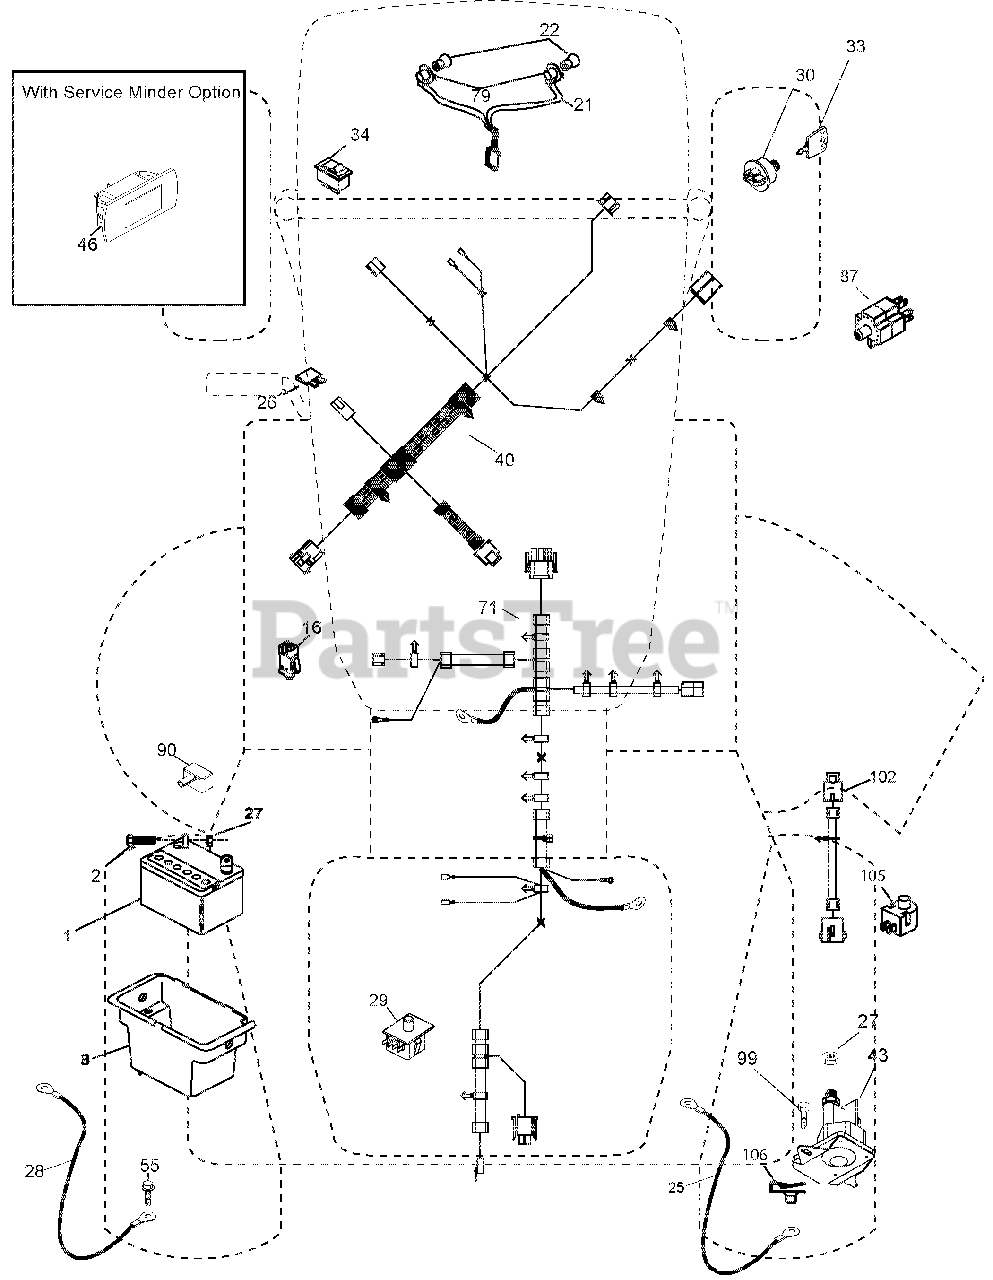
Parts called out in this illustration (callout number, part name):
1	BATTERY.12.VOLT.28.AMP.WET
2	BOLT.HEX.HD.1/4-20UNC X 3/4
8	BOX.BATTERY.MNT.REAR.LT.TEX.BL
16	SWITCH.INTERLOCK.NONO.GRAY
21	HARNESS ASM.LIGHT.22"(4152J)
22	BULB.LIGHT.#1156
25	CABLE STARTER 6 G4. BL/RED14.5
26	FUSE.20 AMP.
27	Nut, Keps Hex 1/4-20 unc
28	CABLE.BLACK.22"REAR BATT.TEX
29	SWITCH.SEAT.DELTA.OPC.9LB.
30	SWITCH.IGN.DLTA.P-IN.ROS
33	KEY/CHAIN.BLISTER PACK.GEN.USA
34	SWITCH.LIGHT/RESET.B/B/RED.
40	HARNESS.IGN.DASH.CBL.YTGT.PRED
43	SOLENOID.W/BRASS PLUNGER.2005
55	SCREW.5/16-18X3/4.SMGML.TAP/R
71	HARNESS.IGN.CHASSIS.TEX
79	SOCKET ASM.BULB.TWISTLOCK
87	SWITCH.INTRLCK.CLUTCH.CABLE.TX
90	COVER TERMINAL BATTERY FR. TEX
102	HARNESS.PIGTAIL
105	SWITCH.REVERSE.TT.PEDAL CONTRO
